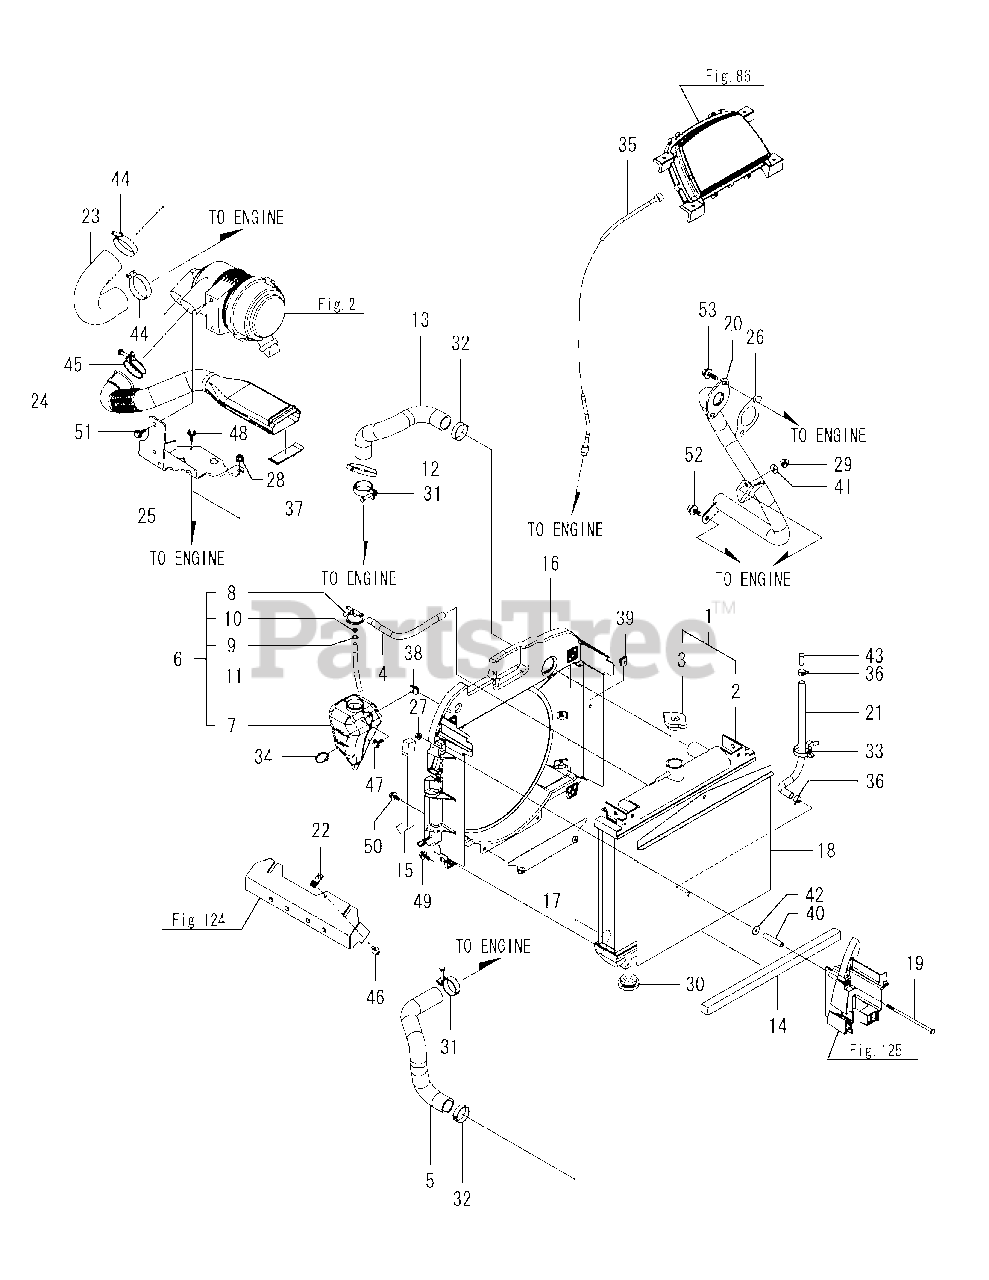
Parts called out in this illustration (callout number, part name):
3	CAP, RADIATOR D46
5	PIPE L 66,COOL.WATER
6	TANK ASSY, COOLANT
13	HOSE, COOLING WATER
15	SEAL,SHROUD LOWER
16	SHROUDM ASSY,FAN
17	PLATE ASSY,SHROUD
18	SCREEN,RADIATOR
22	PLATE ASSY,MOUNT
23	HOSE, AIR INTAKE
24	AIR INTAKE PIPE
25	BRACKET ASSY, AIR CLEANER
27	NUT W/WASHER 6
28	NUT W/WASHER 8
29	NUT W/WASHER 8
35	CABLE, HOUR METER
37	SEAL E,LADIATOR
40	COLLER, 6.5X10X52
41	WASHER 8, POLISHED
46	BOLT M 6X 12 PLATED
47	BOLT M 6X 16 PLATED
48	BOLT M 6X 16 PLATED
49	BOLT M 6X 16 PLATED
50	BOLT M 6X 16 PLATED
51	BOLT M 8X 16 PLATED
52	BOLT M 8X 16 PLATED
53	BOLT M 8X 25 PLATED
